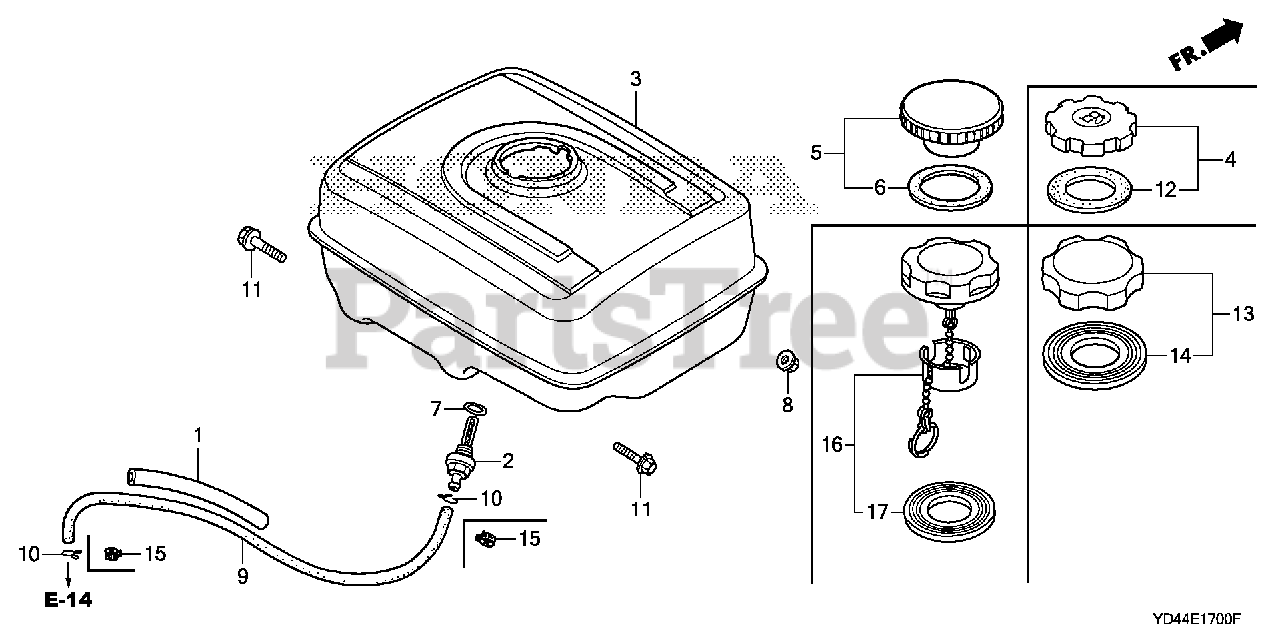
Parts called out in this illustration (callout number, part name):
1	RUBBER, SUPPORTER (107MM)
2	JOINT, FUEL TANK
3	TANK, FUEL *NH31* (MCKINLEY WHITE)
4	CAP, FUEL FILLER (BLACK)
7	O-RING (13.5X1.5) (ARAI)
7	O-RING (14MM) (NOK)
8	NUT, FLANGE (8MM)
9	BULK HOSE, FUEL (4.5X3000) (4.5X235)
10	CLIP, TUBE (B8)
11	BOLT, FLANGE (8X25)
12	GASKET, FUEL FILLER CAP (39X58X3)
